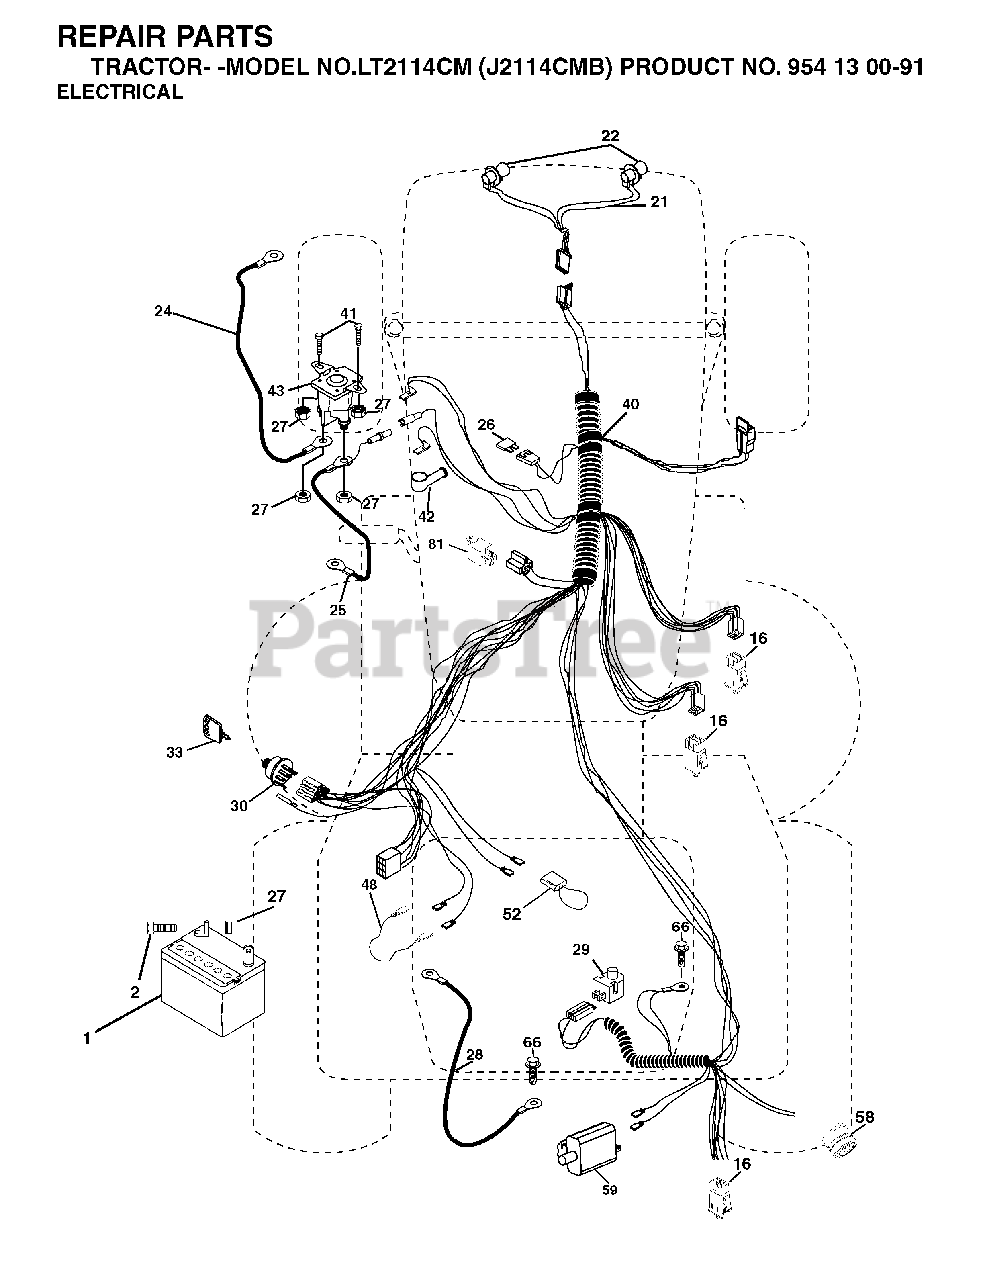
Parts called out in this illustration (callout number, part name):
1	REPL BY 532 12 38-99
16	SWITCH INTERLOOK PUSH-IN
21	HARNESS.W/LIGHT SOCKET
22	LIGHTBULB
24	BATTERY CABLE GT
25	CABLE BATTERY
26	FUSE 20AMP
27	NUT
28	CABLE GROUND
29	PLUNGER SWITCH (COLOR:OLIVE)
30	IGNITION SWITCH
33	KEY MLD GEN DELTA
42	TERMINAL COVER
43	SOLENOID
52	WIRE PROTECTION LOOP
58	BUZZER
81	RELAY.ASSY.T
